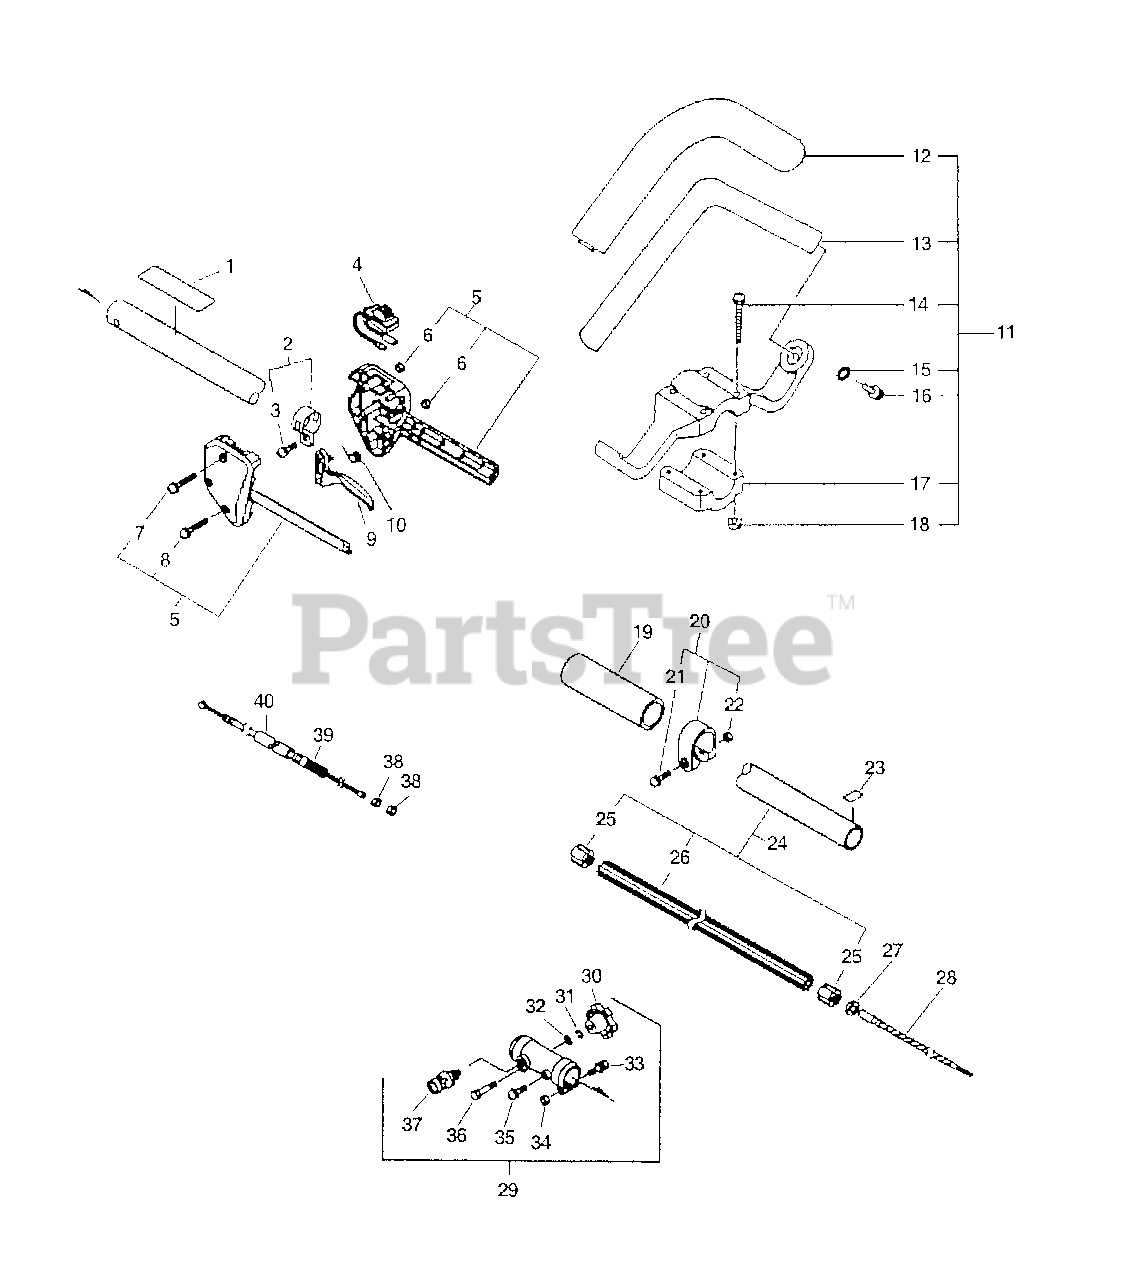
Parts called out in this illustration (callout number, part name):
1	LABEL - CAUTION -- SPANISH
2	CLAMP KIT
3	SCREW - 5X14
4	IGNITION SWITCH ASSY
5	CONTROL HANDLE KIT
7	SCREW - 5X35
8	SCREW - 5X25
9	TRIGGER, THROTTLE
10	SPRING, TRIGGER
11	HANDLE ASSY - FRONT
12	GRIP, HANDLE
13	HANDLE - FRONT
14	SCREW - 5X35
15	WASHER - 5
16	SCREW - 5X20
17	BRACKET, HANDLE - LOWER
19	GRIP, HANDLE
20	CLAMP KIT
21	SCREW - 5X28
23	LABEL - ALIGNMENT
24	MAIN PIPE ASSY
26	LINER - FLEXIBLE
28	DRIVESHAFT - FLEXIBLE -- UPPER
29	COUPLER ASSY
30	KNOB, FASTENER
31	LOCKWASHER - 5
32	WASHER - 5
33	SCREW - 5X30
35	SCREW - 5X12
36	BOLT - 5X35
37	LATCH ASSY
39	CABLE, THROTTLE
